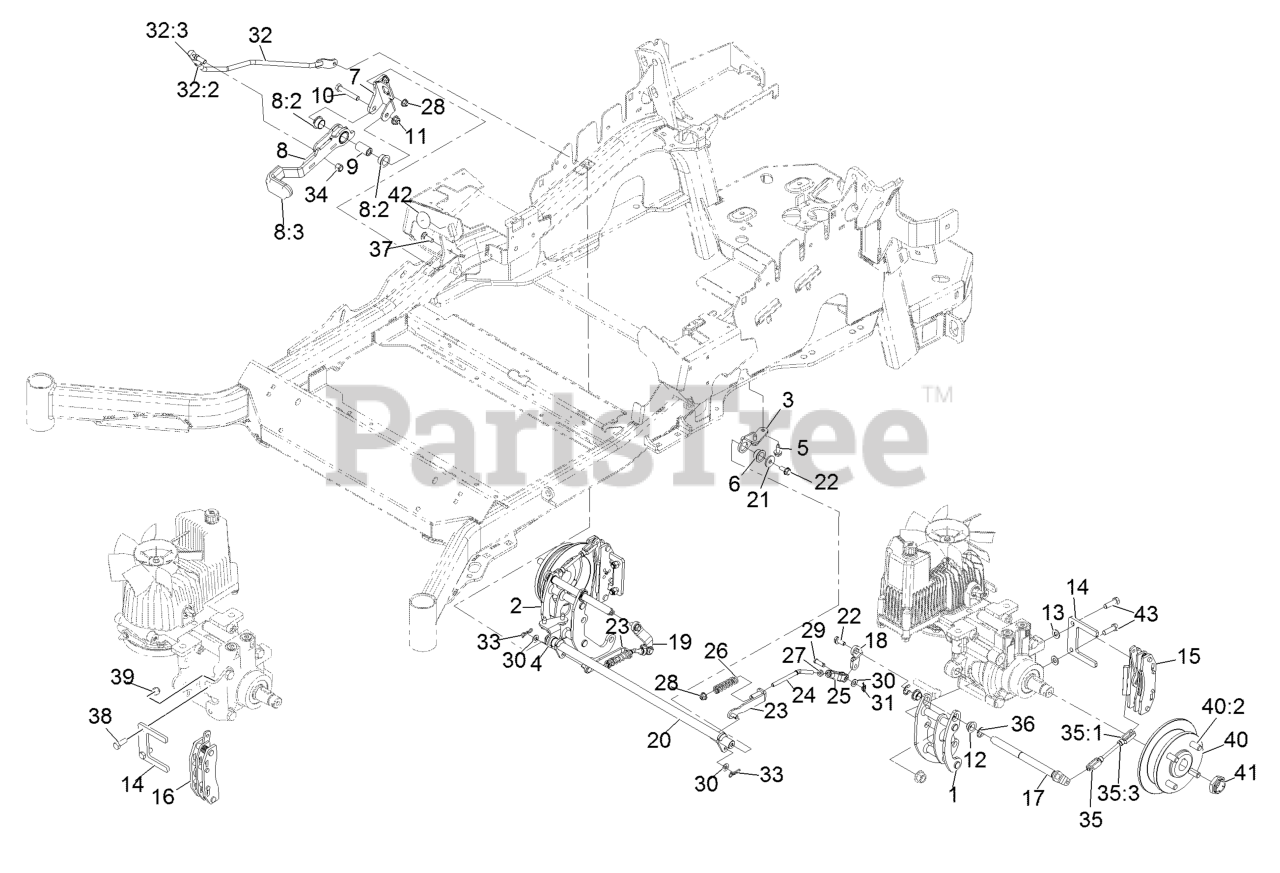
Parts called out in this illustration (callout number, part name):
3	MOUNT-PIVOT, LH
4	MOUNT-PIVOT, RH
5	Screw-HWH 5/16-18 X 3/4 Tf
6	BUSHING-FLANGE
7	BRACKET-MOUNT
8	BRAKE LEVER ASM
8:2	BUSHING-FLANGE
8:3	GRIP-LEVER
9	HANDLE-PIVOT, BRAKE
10	SCREW-HH
11	NUT-HF, NI
12	BUSHING
13	WASHER-FLAT
14	PLATE-MOUNT, BRAKE
15	CALIPER-BRAKE
16	CALIPER-BRAKE, RH
18	ARM-INNER, LH
19	ARM-INNER, RH
20	SHAFT-CROSS
21	WASHER-FLAT
22	SCREW-HHF
23	BRACKET-L
24	LINKAGE-MID
25	YOKE-OFFSET
26	SPRING-COMPRESSION
27	NUT-JAM
28	NUT-HF, NI
29	PIN-CLEVIS
30	WASHER-PLAIN
31	PIN-COTTER, LOCKING
32	FRONT LINKAGE ASM
32:2	END-TIE ROD, RH
32:3	NUT-HJ
33	PIN-COTTER, LOCKING
34	NUT-LOCK
35	REAR LINKAGE ASM
35:3	NUT-JAM
37	BOLT-CARR
38	SCREW-HH
39	NUT-LOCK, NI
40	WHEEL HUB ASM
40:2	STUD-WHEEL
41	LOCKNUT
42	DECAL-COVER
43	SCREW-LOCK, PATCH
